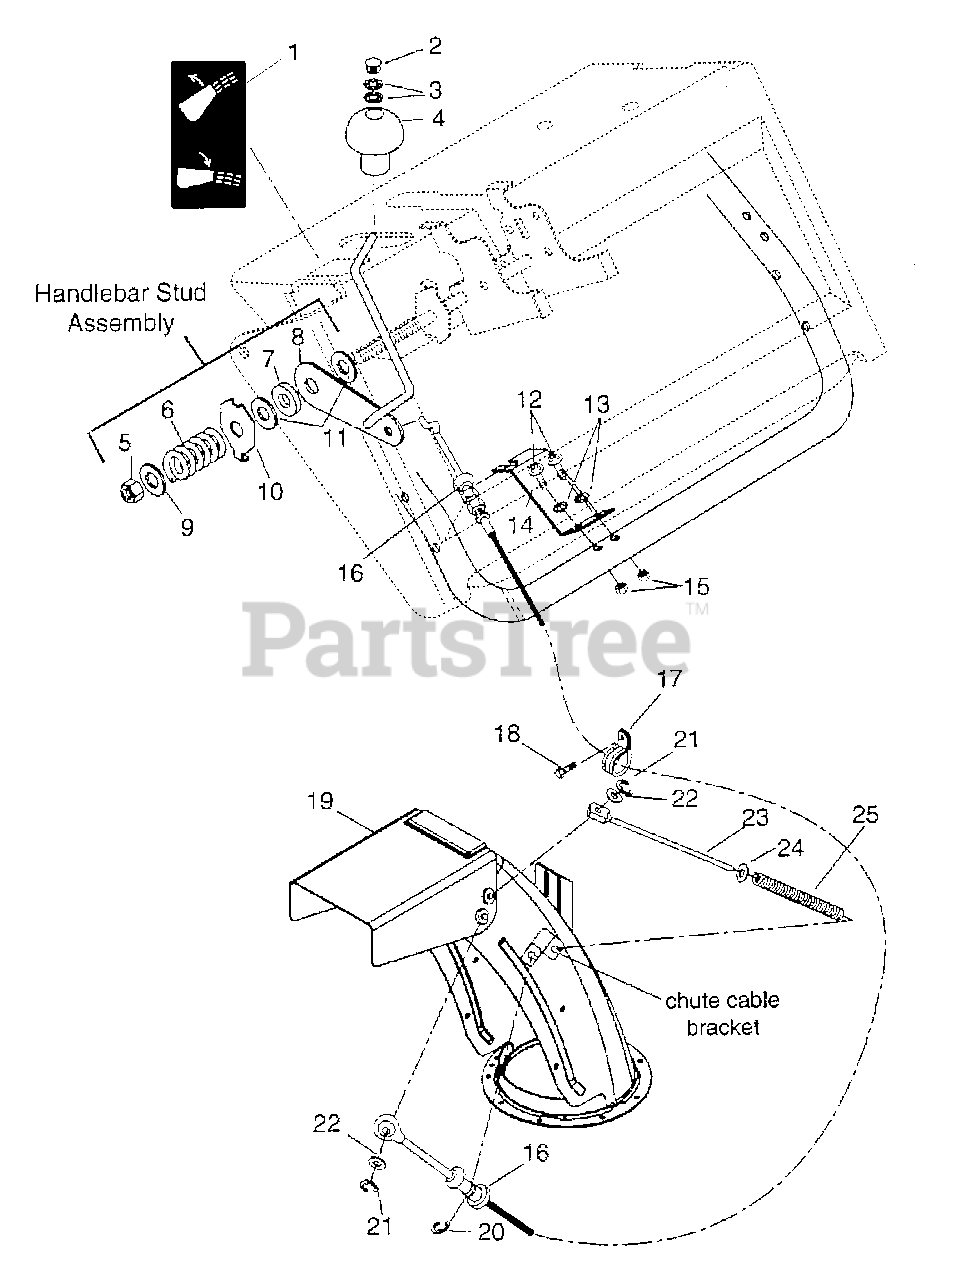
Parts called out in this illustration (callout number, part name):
1	DECAL, DEFLECTOR CONTROL
2	HOLE PLUG
3	RG-RTNG-EXT .375X.010
5	@NUT-LK-CTR .38-16 YWZC
6	SG-COMP .187X.56X1.62
7	SPACER .406X.620X.125
8	LEVER-DEFLECTOR
9	@WSHR-FL-STL.406X.812X.065 YWZ
10	PRESSURE FLANGE
11	FRICTION WASHER
12	SCR-MCH .25-20X1.5 PH OVL HD Y
13	WSHR-LK-EXT .250 TTH CNTRSNK
14	BRACKET, DEFLECTOR CABLE
15	@NUT-LK-CTR .25-20 YWZC
16	CABLE-DEFLECTOR CONTROL
17	CLAMP, CUSHIONED STEEL
18	@BLT-HEX .38-16X.75 GR5 YWZC
19	CHUTE, DISCHARGE
20	RG-RTNG-EXT .375X.035 TYP E
21	RG-RTNG-EXT .218X.035 TYPE E
22	@WSHR-FL-STL.281X.62X.065 YWZC
23	HOUSING, BLOWER - 28"
24	@WSHR-FL-STL.344X.688X.065YWZC
25	SPRING, COMP. .08 X .40 X 7.15
